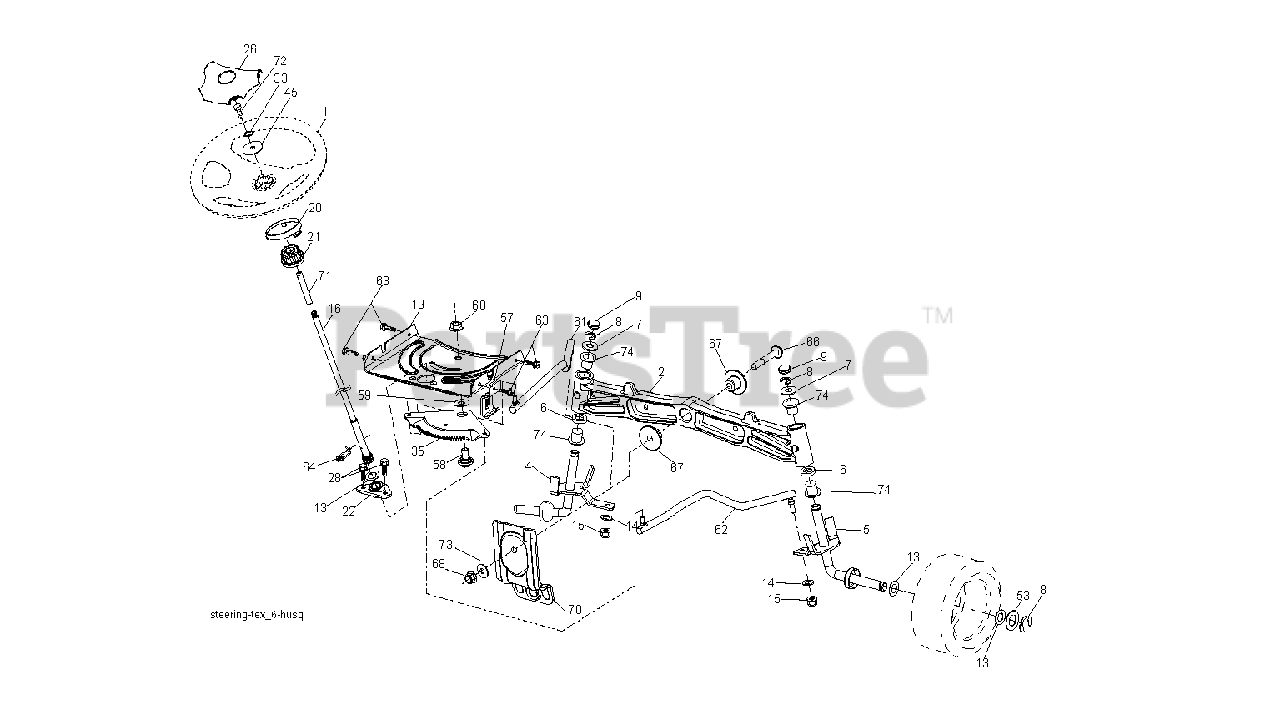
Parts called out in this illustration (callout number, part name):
1	WHEEL.STEERING.PREM.2.BLK
2	AXLE.HALF.ASM.WELDED
4	SPINDLE.WELDED.LH.15"TEX
5	SPINDLE.WELDED.RH.15"T
8	RING CLIP
9	CAP.SPINDLE
14	WASHER, LOCK 3/8
15	NUT CROWNLOCK 3/8-24
16	SHAFT STEERING
19	PLATE.STEER.DDL.NLT/NG
20	BOOT STEERING BLACK
21	ADAPTER, WHEEL STNG..
22	BUSHING.ASM.STEERING.A
26	INSERT.CAP.STRG.WH.BLACK
28	SCREW, 3/8-16X3/4
33	LOCKWASHER
35	GEAR.SECTOR.PLATE.DDL.
45	WASHER.11/32
53	WASHER.HARDENED
57	BRACKET.UPSTOP.TEX
58	BOLT.SHOULDER.SECTOR.P
59	WASHER.THURST.SECTOR.S
60	NUT FLANGE LOCK 5/8-11
61	DRAGLINK.LH.BALLSTUD.D
62	DRAGLINK.RH.BALLSTUD.D
63	SCREW
64	RETAINER.CLIP.SPRING.S
66	BOLT HEX FGHD 7/16-14 X 3 SERR
67	BUSHING.PM.FRONT AXLE
68	NUT.LOCK.FLANGE.7/16
70	BRKT.DECK.SUSPENSION.F
71	SHAFT EXTENSION STEERING
72	BOLT YT
73	WASHER.1.5X.505X.118
74	BRNG T
